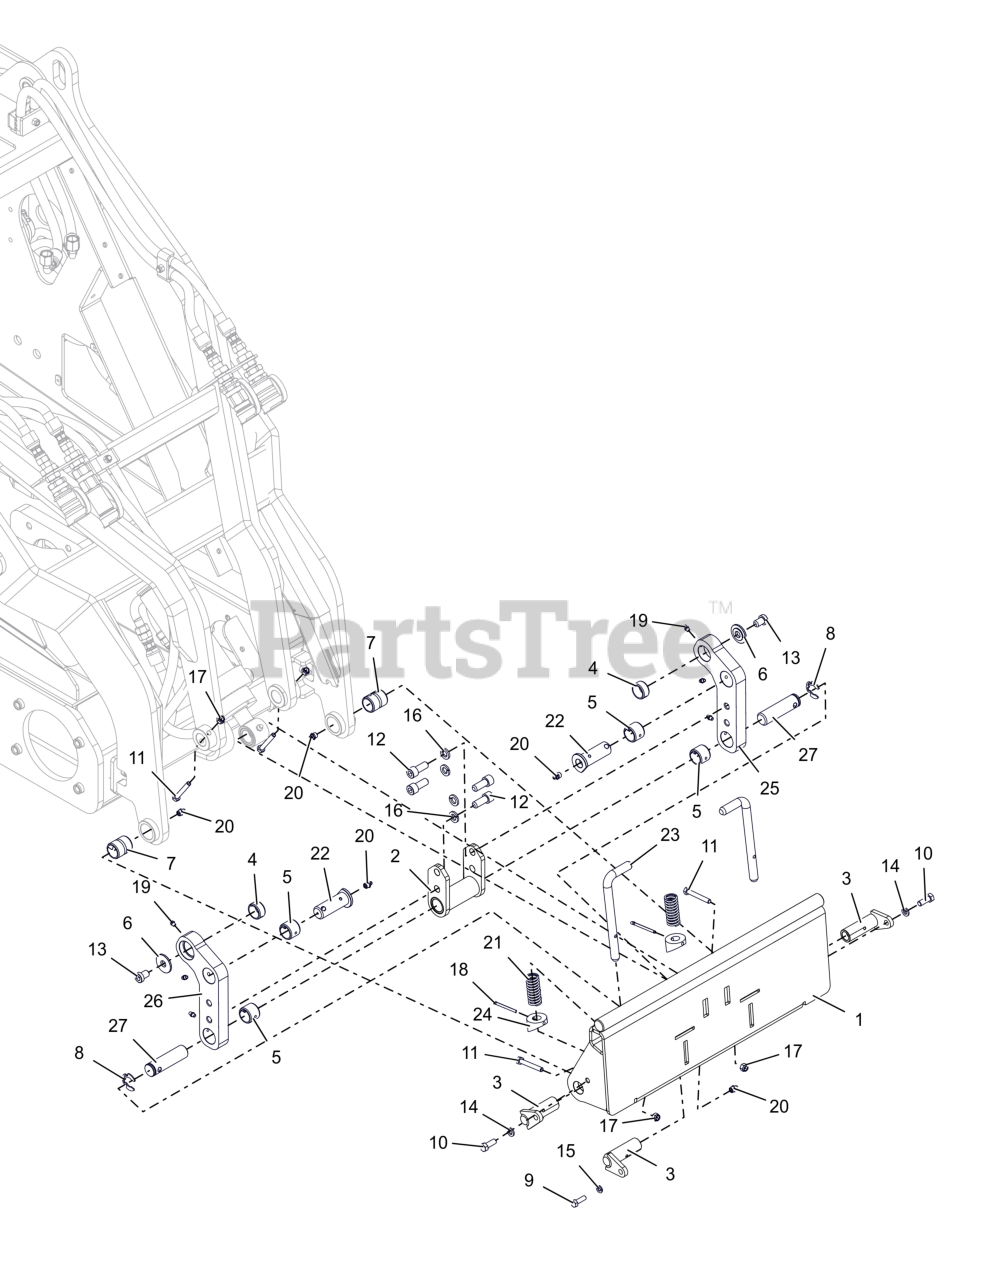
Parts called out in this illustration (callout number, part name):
1	WLDMT, Q-TACH (BLACK)
2	SUPPORT, TILT-CENTER (BLACK)
3	PIN, PLATE ASSY
4	BSHG, HARDENED 1.25ODX1.00IDX.625LG
5	BSHG, HARDENED 1.25ODX1.00IDX1.00LG
6	SPCR, FLANGED
7	BSHG, HARDENED 1.25ODX1.00IDX1.50LG
8	RING- RETAINING-KLIPRING 1.00
9	BLT,HEX .31-18X1.00 G5 ZCC
10	BLT, HEX .38-16X1.00 G8ZCCEP30
11	BLT, HEX .31-18X2.25 G5 ZCC
12	SCR, SKH .500-13X.750 GR8 ZCC
13	SCR, SKH .500-13X.750 GR8 ZCC
14	WSHR,LK-REG .375X.094 ZCC
15	WSHR,LK-REG .312X.078 ZCC
16	WSHR,LK-REG 0.502 X 0.125 ZCC
17	NUT,NYL .31-18 G5 ZCC
18	PIN, CTR .18X2.00 EXTPRSQCT ZCC
19	FTG-LUBE .25-28X.256 SST
20	FITTING, GREASE
21	SPRG, COMPRESSION SPRG, COMPRESSION
22	PIN, PIVOT
23	HANDLE, Q-TACH
24	BUSHING, LIFT
25	SUPPORT, TILT-LH (BLACK)
26	SUPPORT, TILT-RH (BLACK)
27	PIN, TILT
